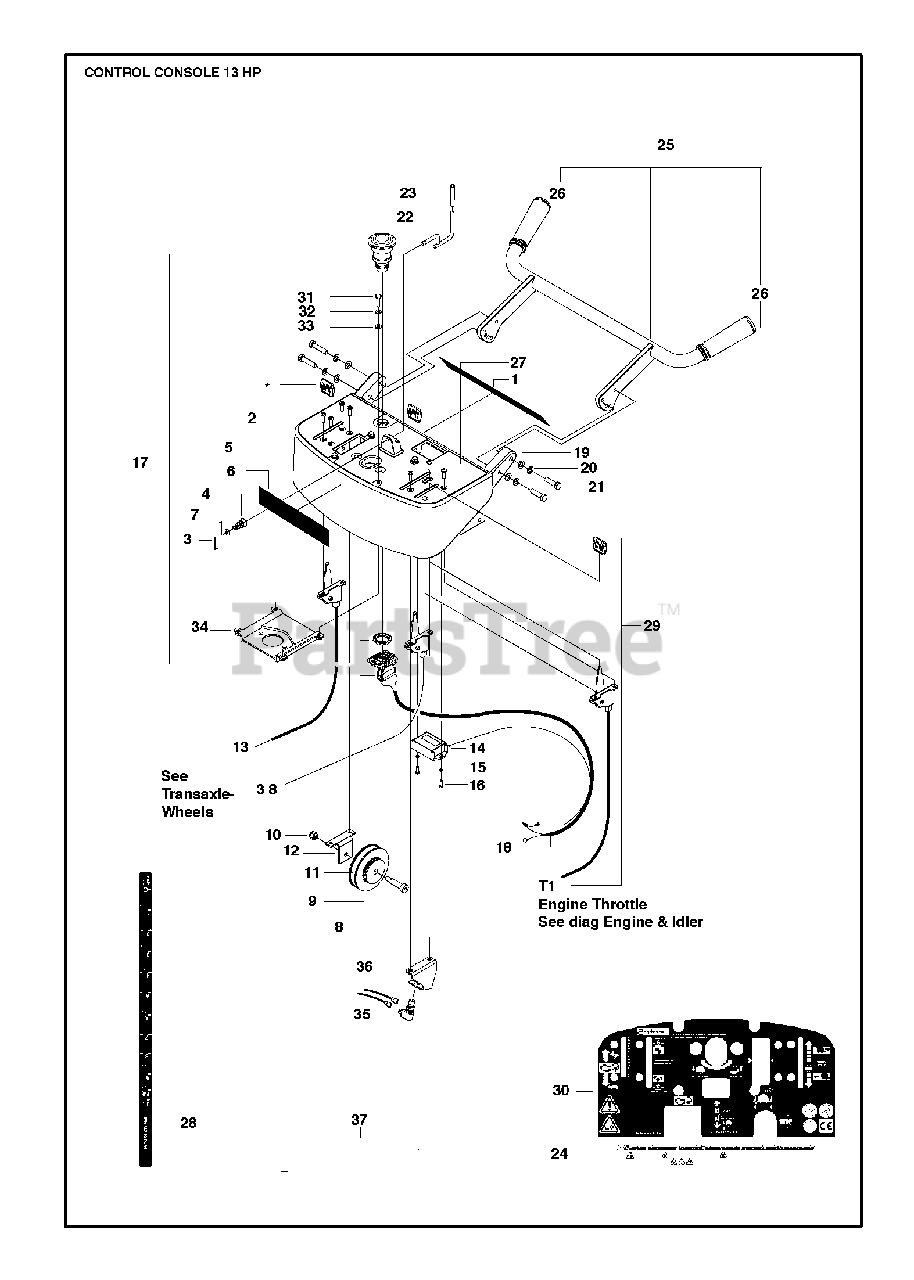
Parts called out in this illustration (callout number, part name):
15	SPRING WASHER 4.1X7.1
19	WASHER
20	SPRING WASHER
